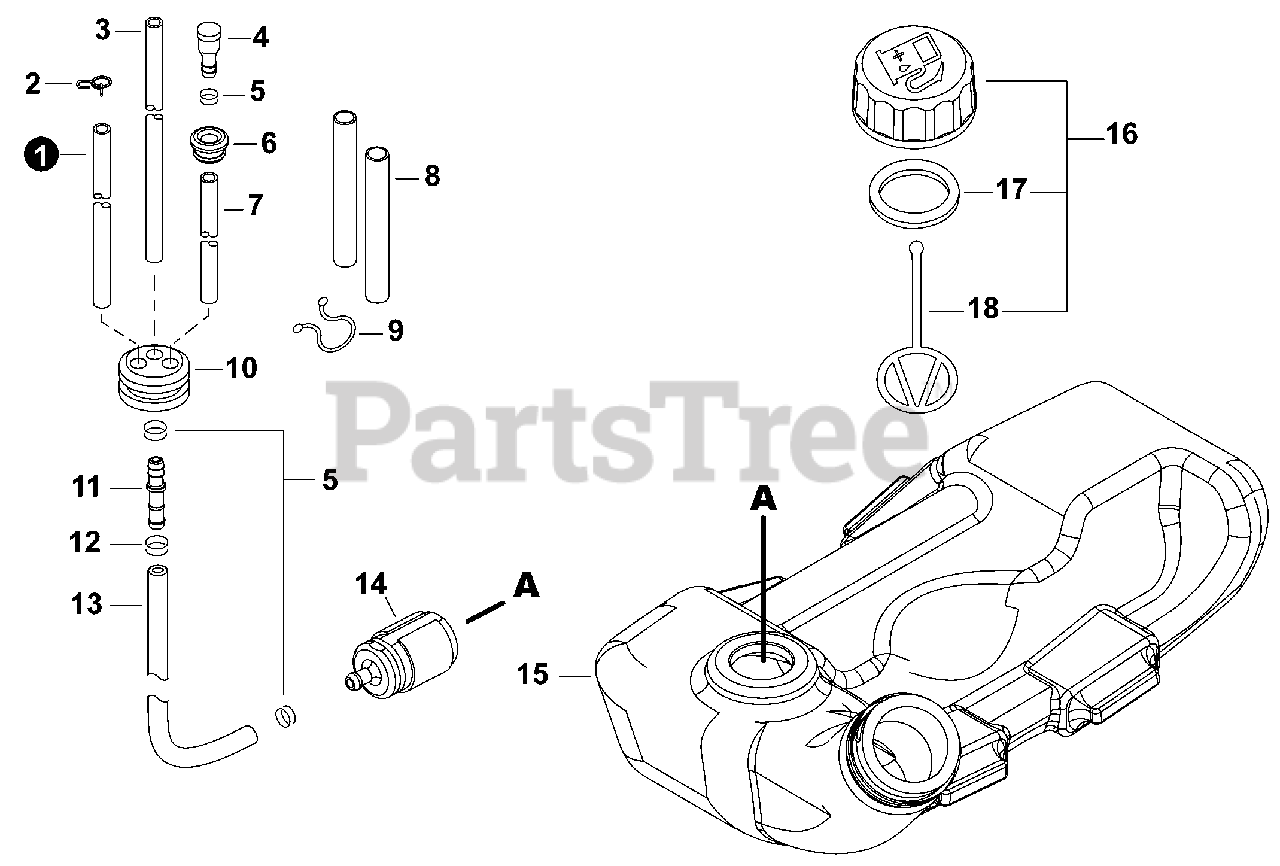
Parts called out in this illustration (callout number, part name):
1	PIPE, FUEL 3x6x120 CLEAR
2	CLIP, SPRING 5.2
3	PIPE, FUEL 3x6x130 BLACK
4	VENT ASSY
6	GROMMET
7	PIPE, FUEL 3x6x135L
8	TUBE, INSULATOR 8x9x80
10	GROMMET, FUEL
11	CONNECTOR, PIPE
12	CLIP 5.5
13	PIPE, FUEL 3x5x180
14	FILTER, FUEL
15	TANK, FUEL
16	CAP ASSY, FUEL
17	GASKET, FUEL CAP
18	CONNECTOR, CAP L= 123
